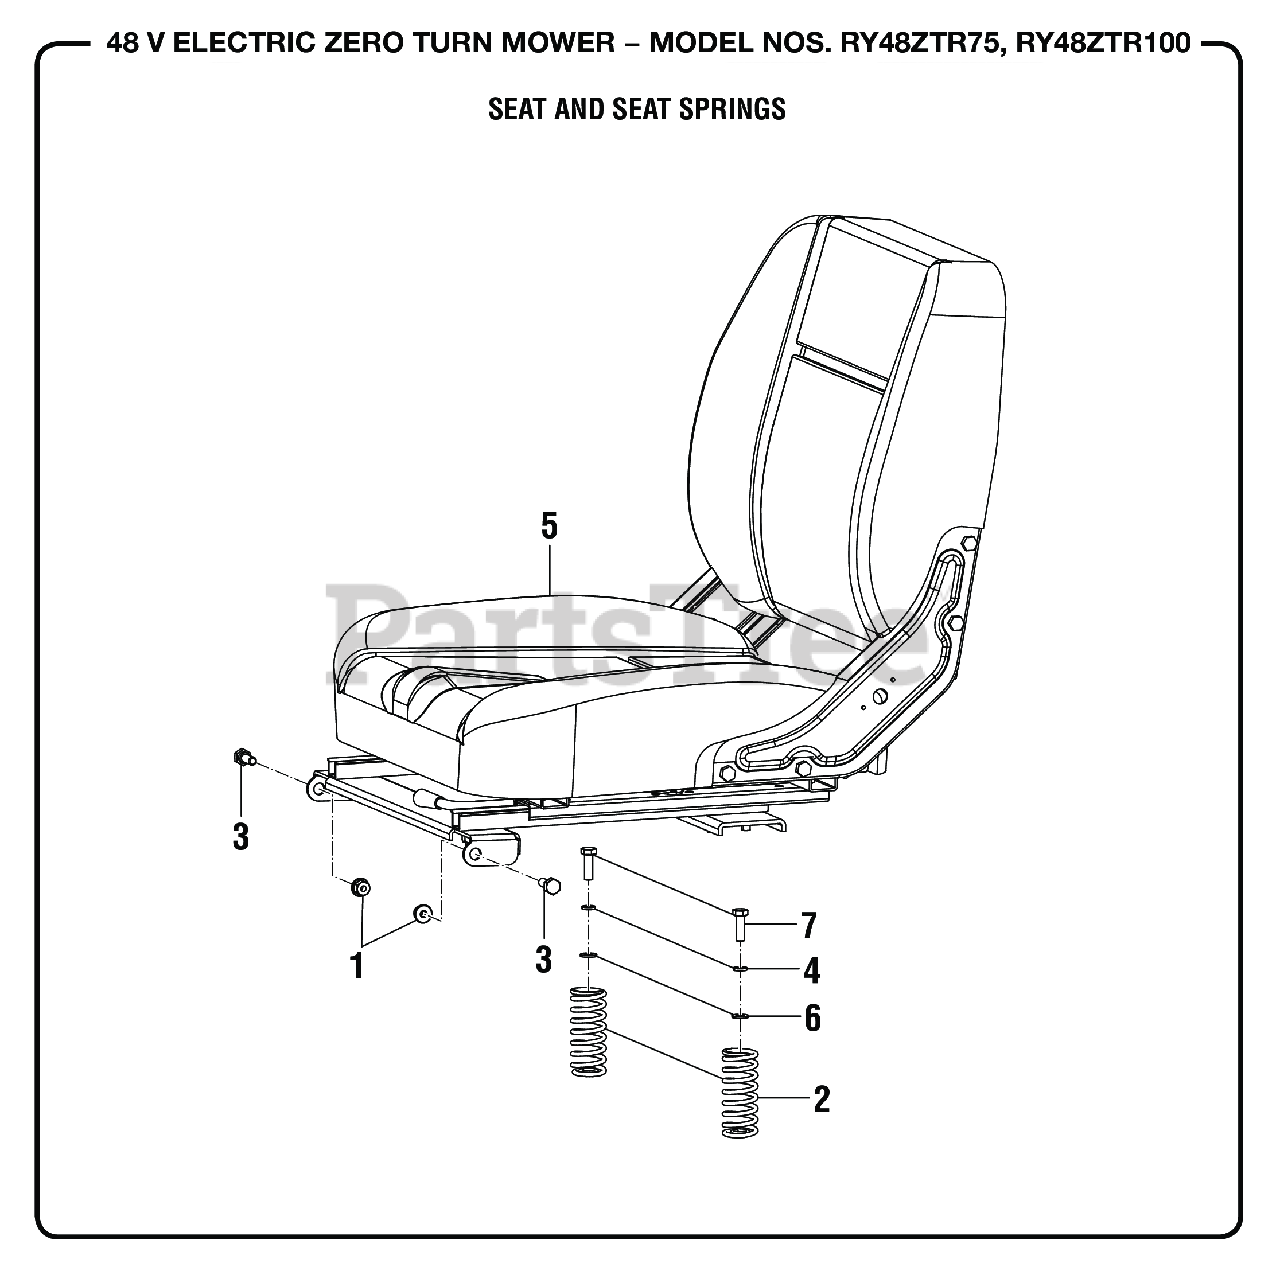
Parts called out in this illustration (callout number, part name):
1	Flange Nut (M8) (For Drive Motor Controller V)
2	Seat Spring, ZTR
3	Shoulder Bolt (M8 x 20 mm)
4	Lock Washer (OD9.8 x ID8.5 x 5t)
5	Seat, ZTR
6	Washer (OD16 x ID8.4 x 1.6t)
7	Bolt (M8 x 25 mm, Hex Hd.)
